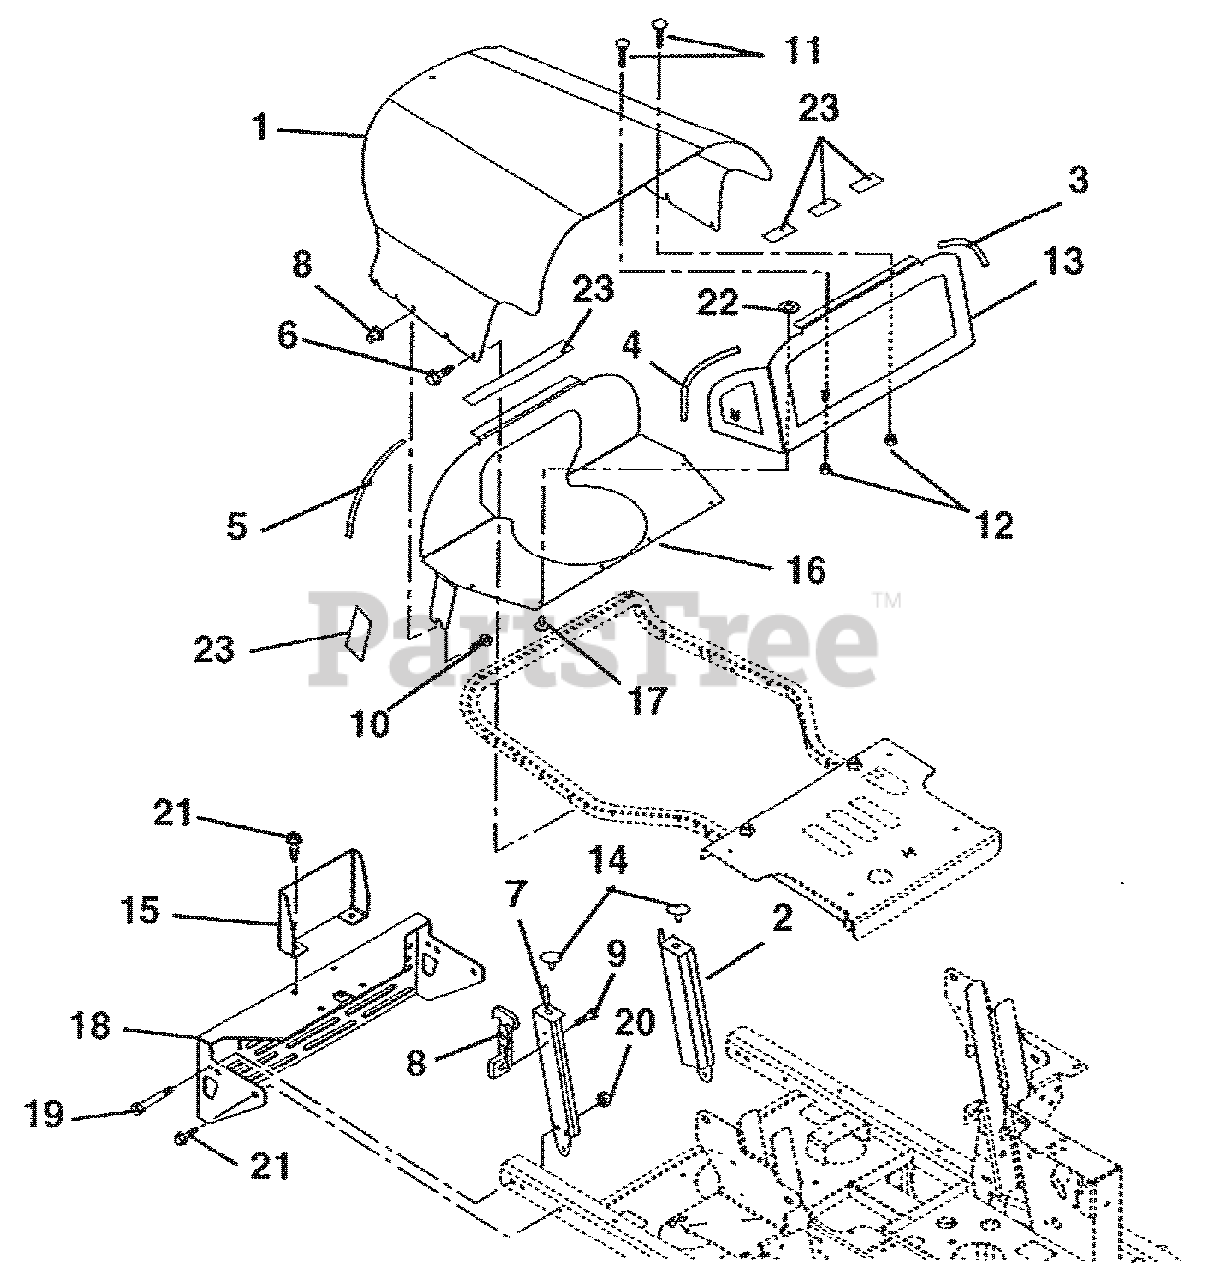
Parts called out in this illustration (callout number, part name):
2	Weldment, Hood Support, Left Hand
3	Seal, Trim Lok Bulk .06 Bubble
4	Seal, Trim Lok Bulk .06 Bubble
5	Seal, Trim Lok Bulk .06 Bubble (069)
6	Screw, Tapping .38-16 x .50 Hex Washer Head
7	Weldment, Hood Support, Right Hand
8	Latch, Rubber
9	Screw, Machine 10-24 x .50 Hex Washer Head
10	Screw, Machine 10-24 x 1.50 Hex Washer Head
11	Bolt-Round Head Square Neck .25-20 x .50 Grade 5
12	Nut-Locking-Top-Flange .25-20
13	Weldment, Plenum
14	Button Bumper
15	Guard, Muffler
16	Support, Plenum
17	Rivet, Pop .18 x .402
18	Bumper, Rear
19	Bolt, Hex .38-16 x 2.75 Grade 5
20	Nut-Locking-Top-Flange .38-16
21	Screw, Tapping .38-16 x .75 Hex Washer Head
22	Washer-Flat-Steel .219 x .50 x .049
23	VHB Ta[e 4941F
